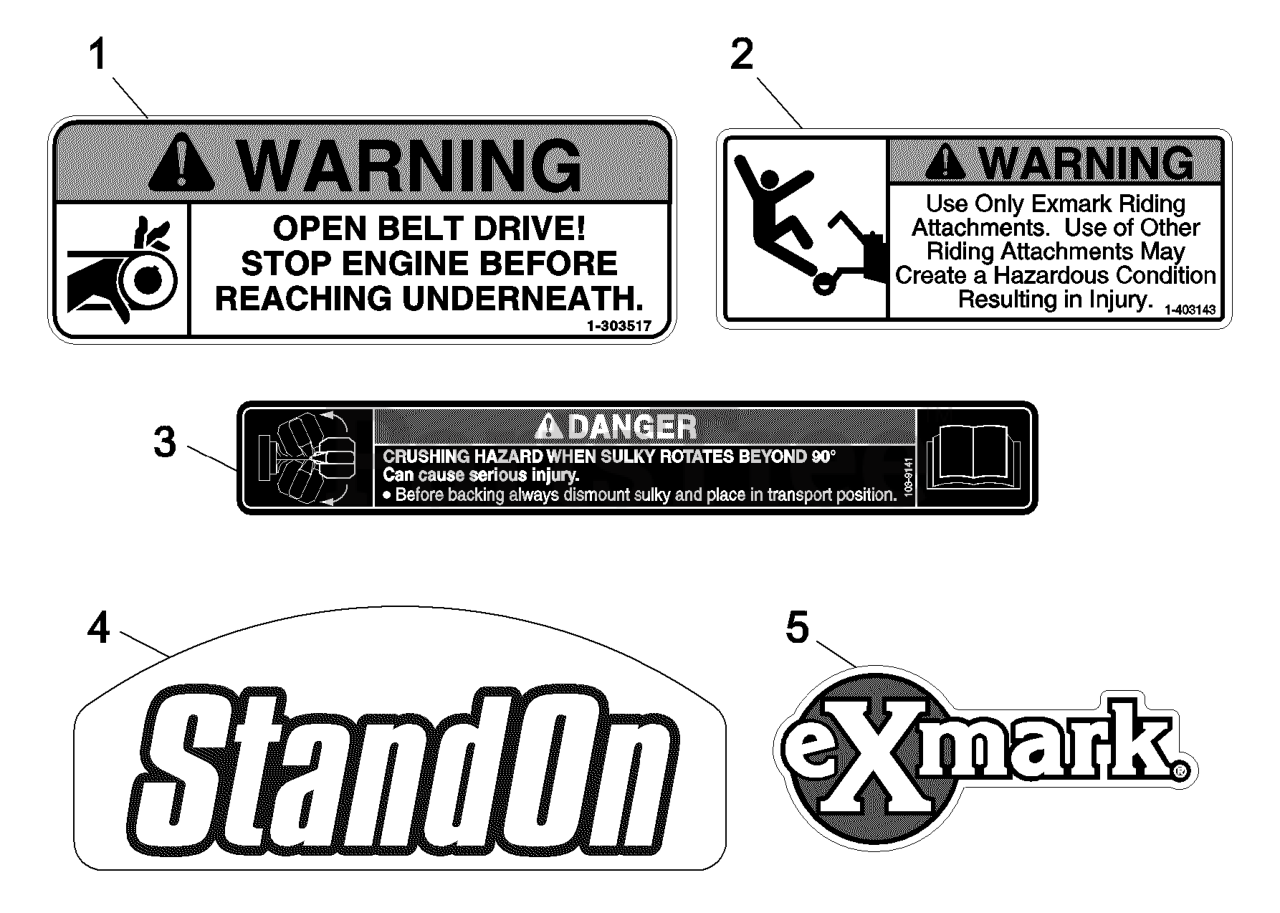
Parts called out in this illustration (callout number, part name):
1	DECAL,BELT DRIVE
2	DECAL,SULKY WARNING
3	DECAL,SULKY
4	DECAL,STANDON
5	DECAL,EXMARK
